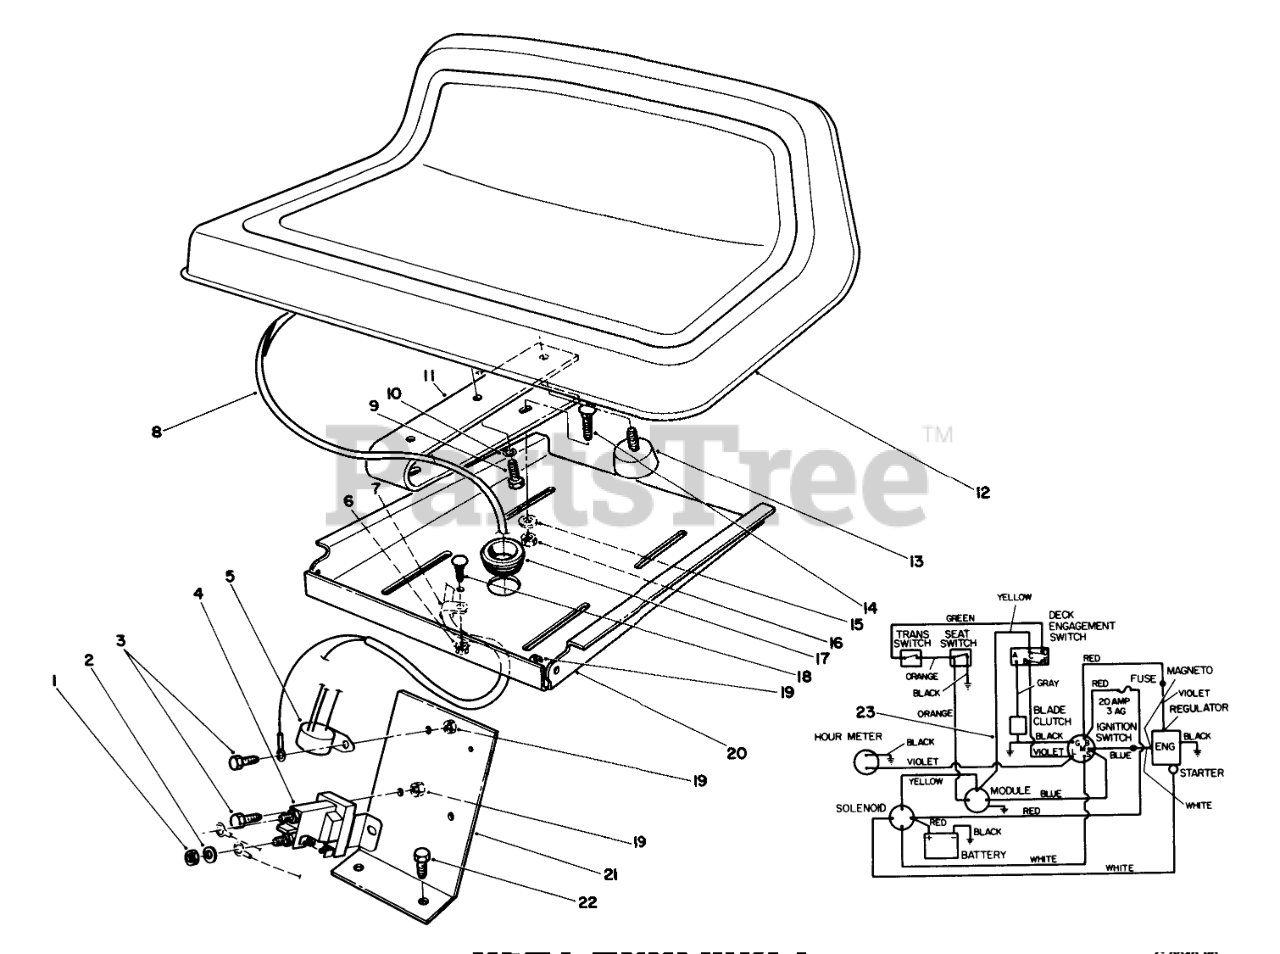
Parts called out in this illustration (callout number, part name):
1	NUT-JAM
2	WASHER-LOCK
3	SCREW-HH
4	SOLENOID
5	KOHLER MODULE
6	NUT-KEPS
7	CLIP-CLOSED, INSULATED
8	SWITCH-SEAT
9	SCREW-HH
10	WASHER-LOCK
11	Spring Seat
13	BUMPER-RUBBER
14	BOLT-CARR
15	WASHER-PLAIN
16	NUT-LOCK, NI
17	GROMMET
18	SCREW-CARR
19	NUT-LOCK, NI
20	SEAT PAN R
21	ELEC COMPONENT PANEL B
22	SCREW-HH
23	WIRE HARNESS - 16 HP
